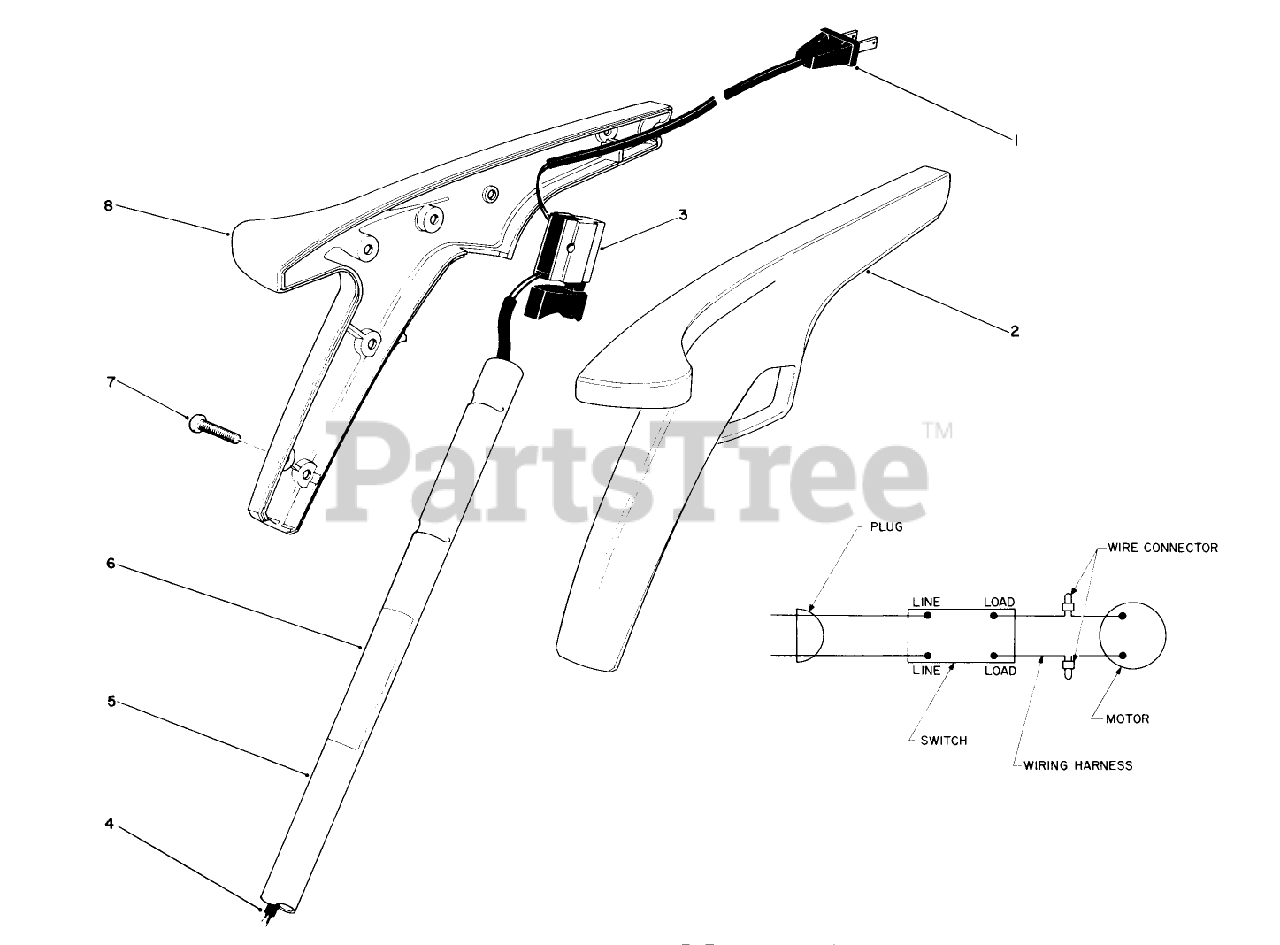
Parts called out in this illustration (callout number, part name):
3	SWITCH SINGLE SPEED
6	Decal, Serial (Canada)
7	#8 X .625" PHILPS PAN H
